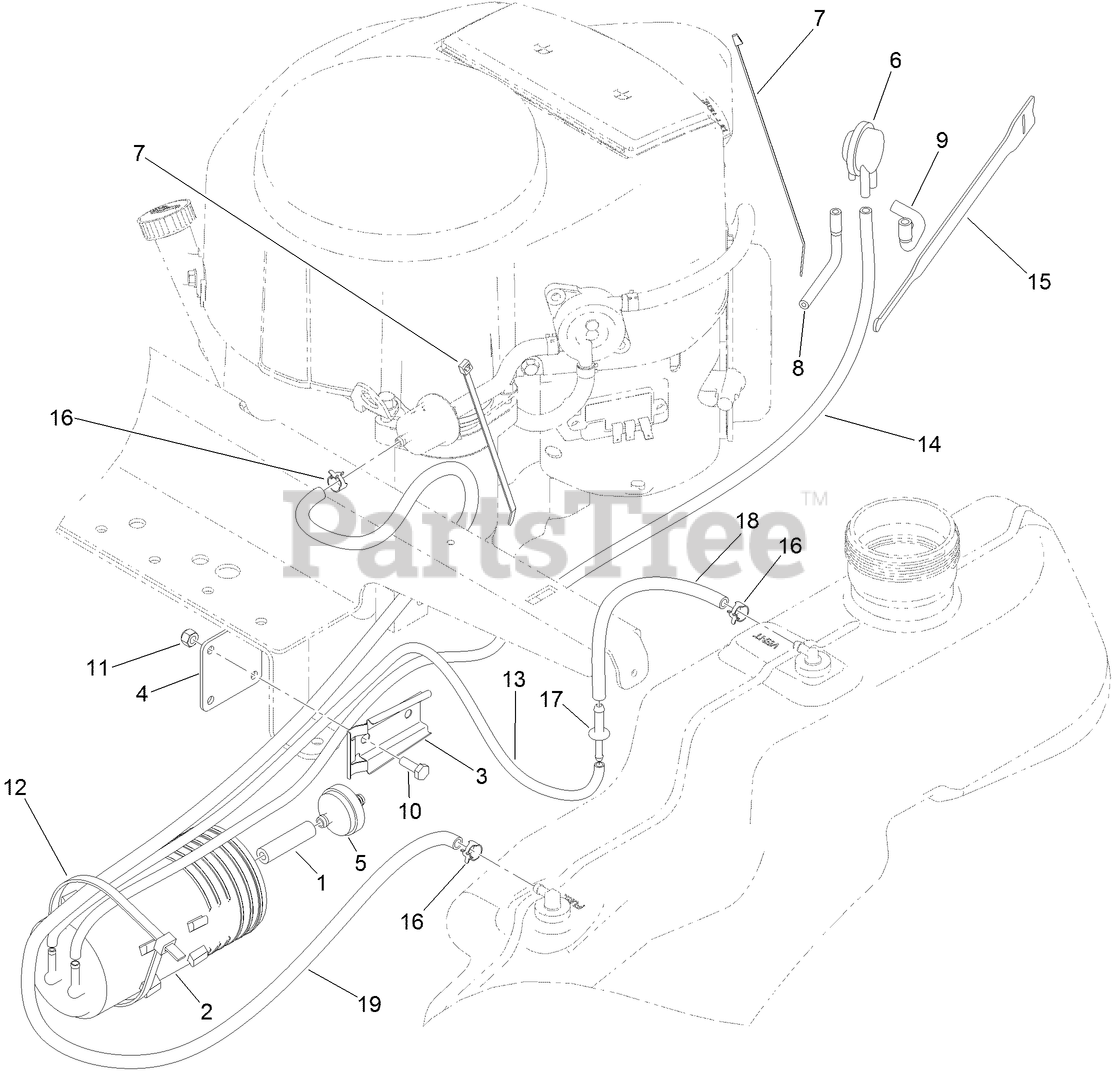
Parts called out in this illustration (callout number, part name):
1	HOSE-FUEL
2	CANISTER-CARBON, 800CC
3	BRACKET-CANISTER, CARBON
4	PLATE-ADAPTER
5	FILTER-FUEL, INLINE
6	VALVE-CONTROL, VACUUM
7	TIE-CABLE
8	HOSE-VENT, FORMED
9	HOSE-VENT, FORMED
10	SCREW-HH
11	NUT-LOCK, NI
12	TIE-CABLE
13	HOSE-FUEL
14	HOSE-FUEL
15	STRAP-VELCRO, CABLE TIE
16	CLAMP-HOSE
17	ADAPTOR-ORIFICE
18	HOSE-FUEL
19	HOSE-FUEL
